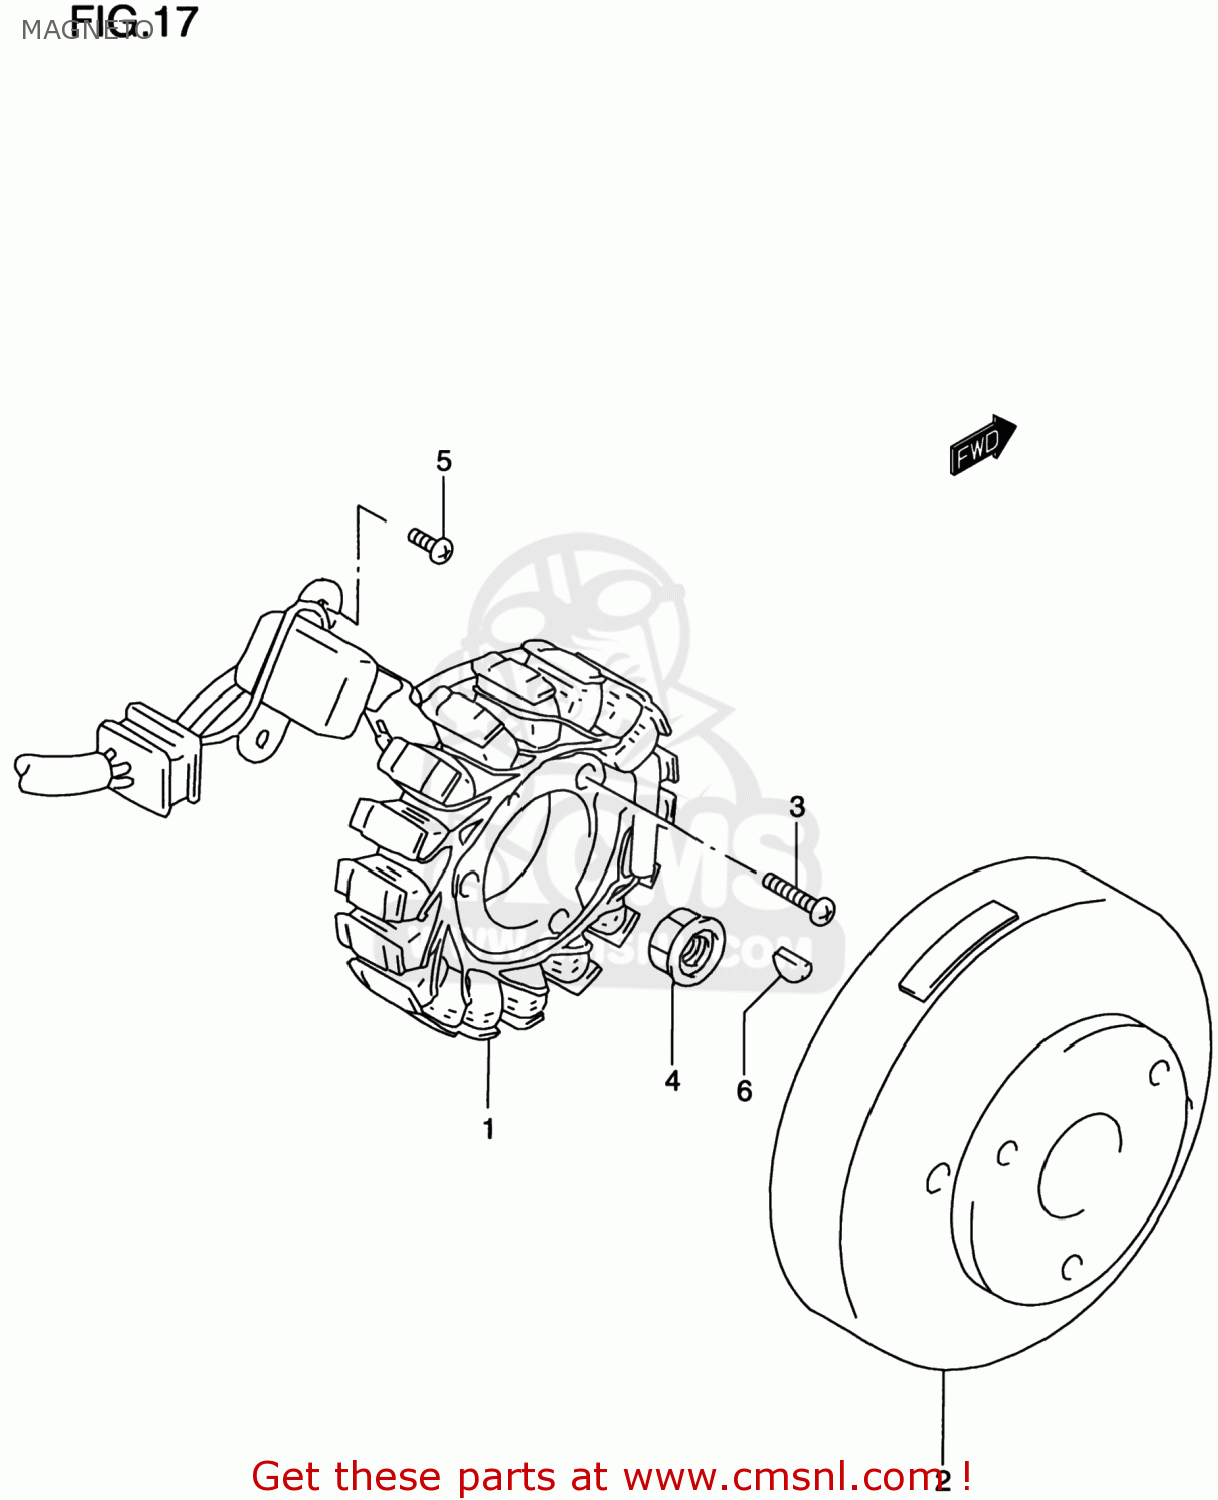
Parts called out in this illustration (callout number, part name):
1	STATOR ASSEMBLY
2	ROTOR ASSY
3	SCREW
4	NUT
5	SCREW
6	KEY
